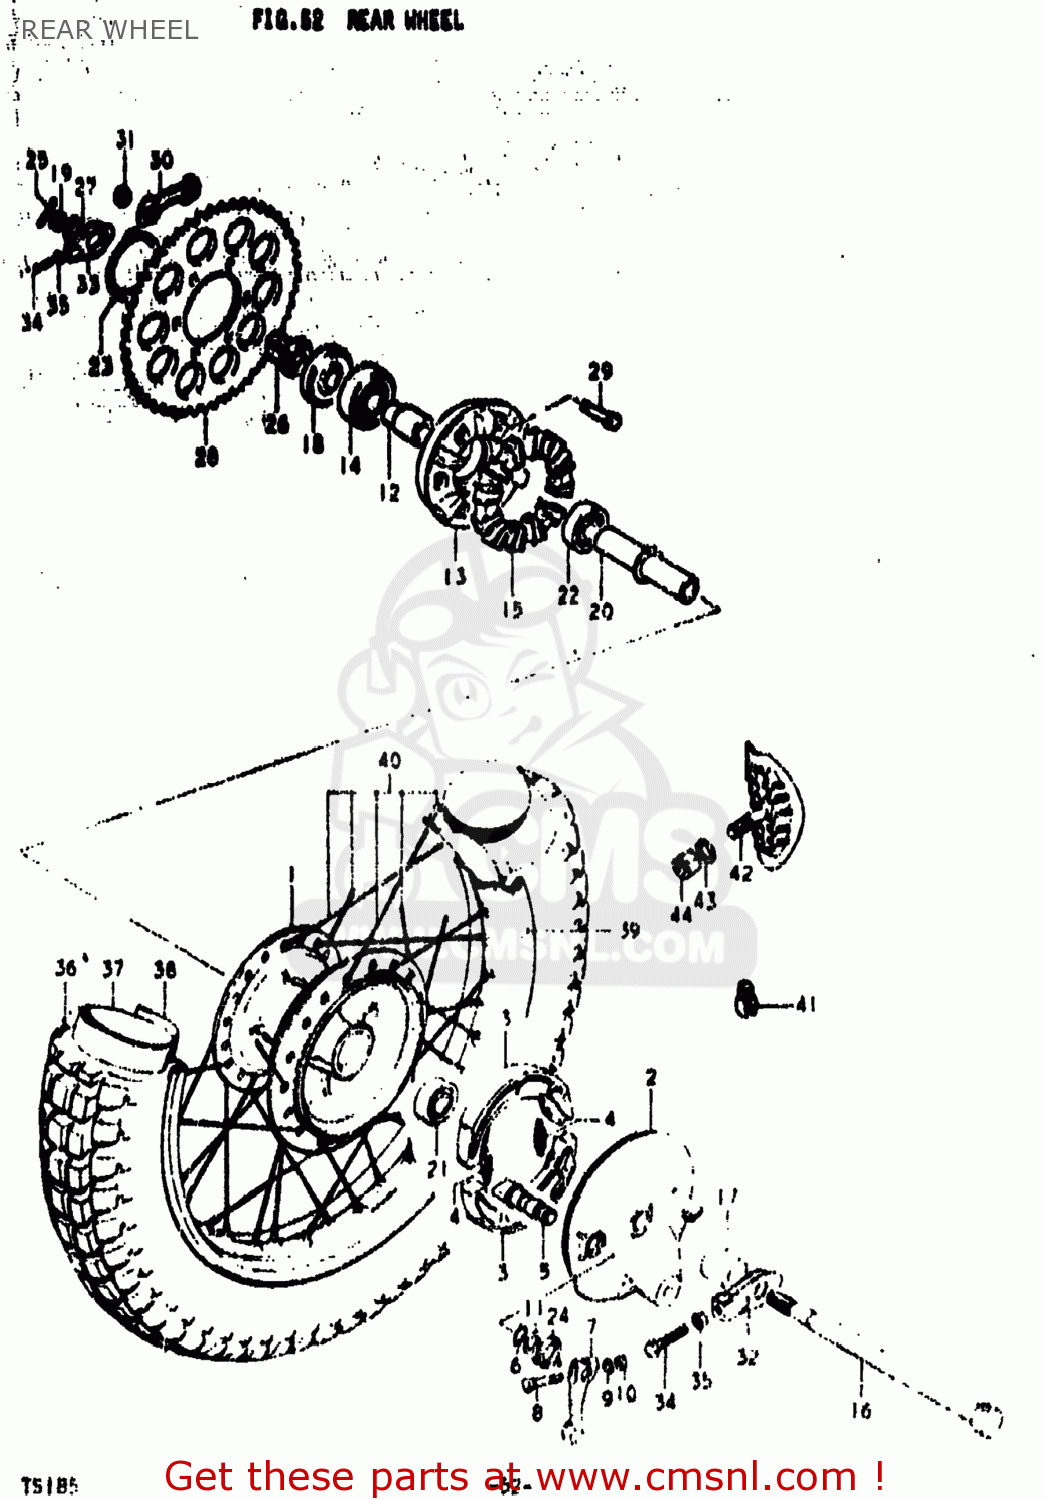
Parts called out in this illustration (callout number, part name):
1	HUB,REAR
2	PANEL,REAR HUB
3	SHOE,BRAKE
4	SPRING(L:34)
5	CAM,FRONT BRAKE
6	O RING(D:2.5,ID:11.4)
7	LEVER,REAR BRAKE CAM
8	BOLT
9	WASHER
10	NUT
11	WASHER(12.5X20X1)
12	SPACER,REAR HUB BEARING
13	DRUM,REAR SPROCKET MOUNT
14	BEARING
15	CUSHION,REAR DRUM
16	AXLE,REAR
17	SPACER
18	SPACER,RR AXLE,L
19	NUT 12MM
20	SPACER
21	BEARING
22	BEARING
23	CIRCLIP
24	SPRING
25	PIN 20X20
26	SPACER,REAR AXLE
27	NUT
28	SPROCKET,REAR
29	BOLT(8X32)
30	WASHER
31	NUT
32	ADJUSTER,CHAIN
33	ADJUSTER,CHAIN
34	BOLT
35	NUT
36	TIRE 3.50-18 089-458MM
37	TUBE ASSEMBLY,WHEEL,INNER
38	PROTECTOR,INNER TUBE
39	RIM,REAR WHEEL
40	SPOKE SET,REAR
41	BALANCER,WHEEL
42	STOPPER,BEAD
43	WASHER
44	NUT
